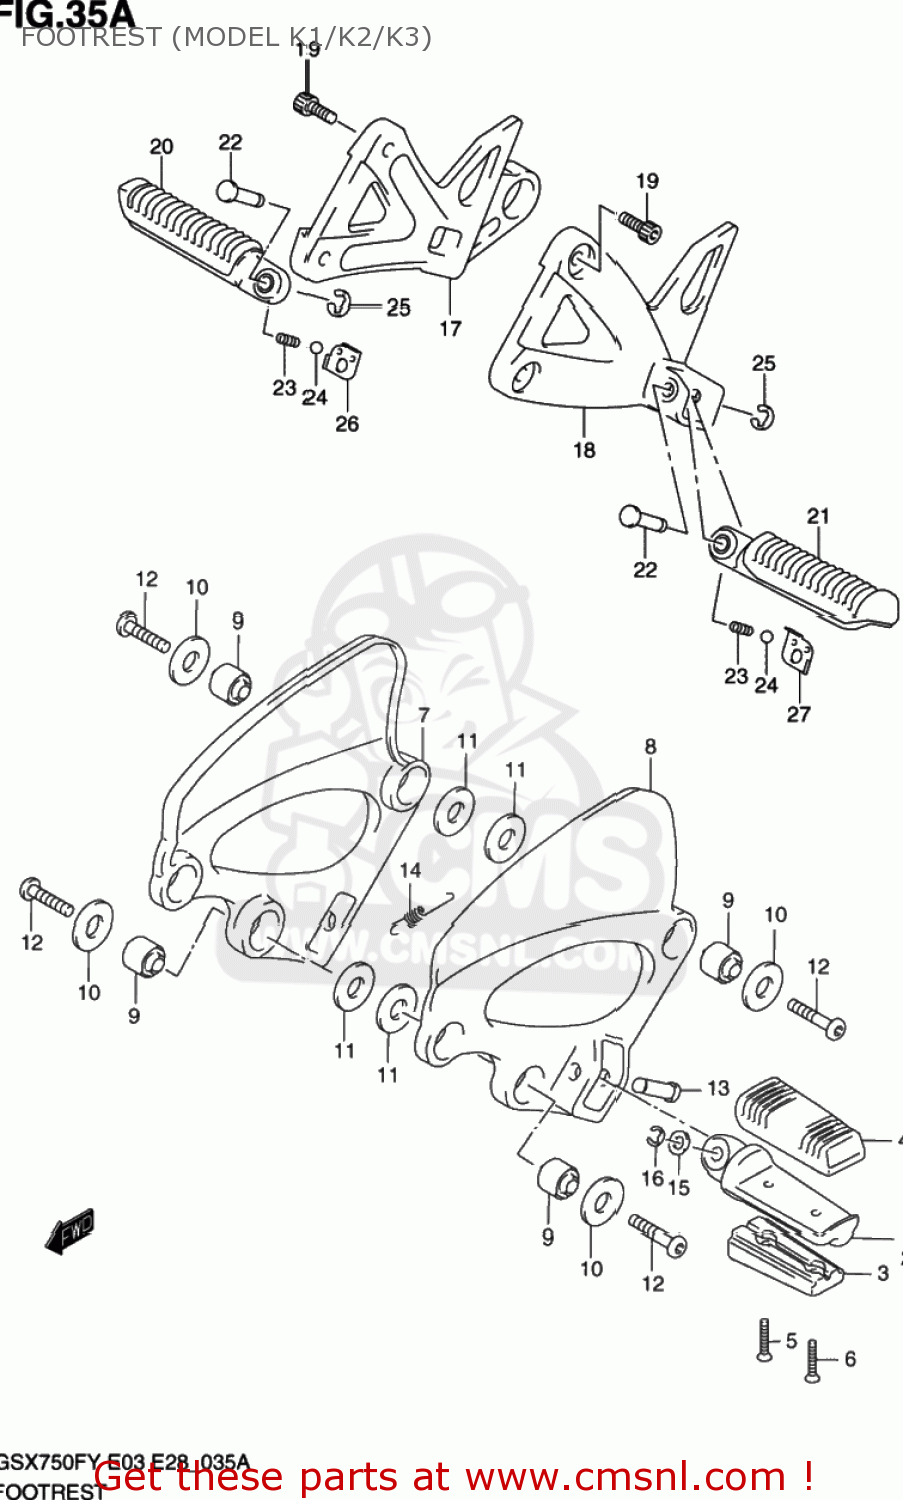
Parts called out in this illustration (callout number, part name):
1	BAR,FR FOOTREST,R
2	BAR,FR FOOTREST,L
3	BAR,FR FOOTREST NO.2
4	RUBBER,FR FOOTREST
5	SCREW, INNER
6	SCREW
7	HOLDER,FR FOOTREST,R
8	HOLDER,FR FOOTREST,L
9	BUSH(8.4X20X16)
10	WASHER(13.7X24X2)
11	WASHER(17.2X24X2.2)
12	BOLT(8X30)
13	PIN(8X33.2)
14	SPRING
15	WASHER
16	E.RING
17	BRACKET,PILLION FOOTREST,R
18	BRACKET,PILLION FOOTREST,L
19	BOLT(8X23)
20	BAR,PILLION FOOTREST,R
21	BAR,PILLION FOOTREST,L
22	PIN
23	SPRING
24	BALL
25	E.RING
26	PLATE,PILLION FOOTREST,R
27	PLATE,PILLION FOOTREST,L
